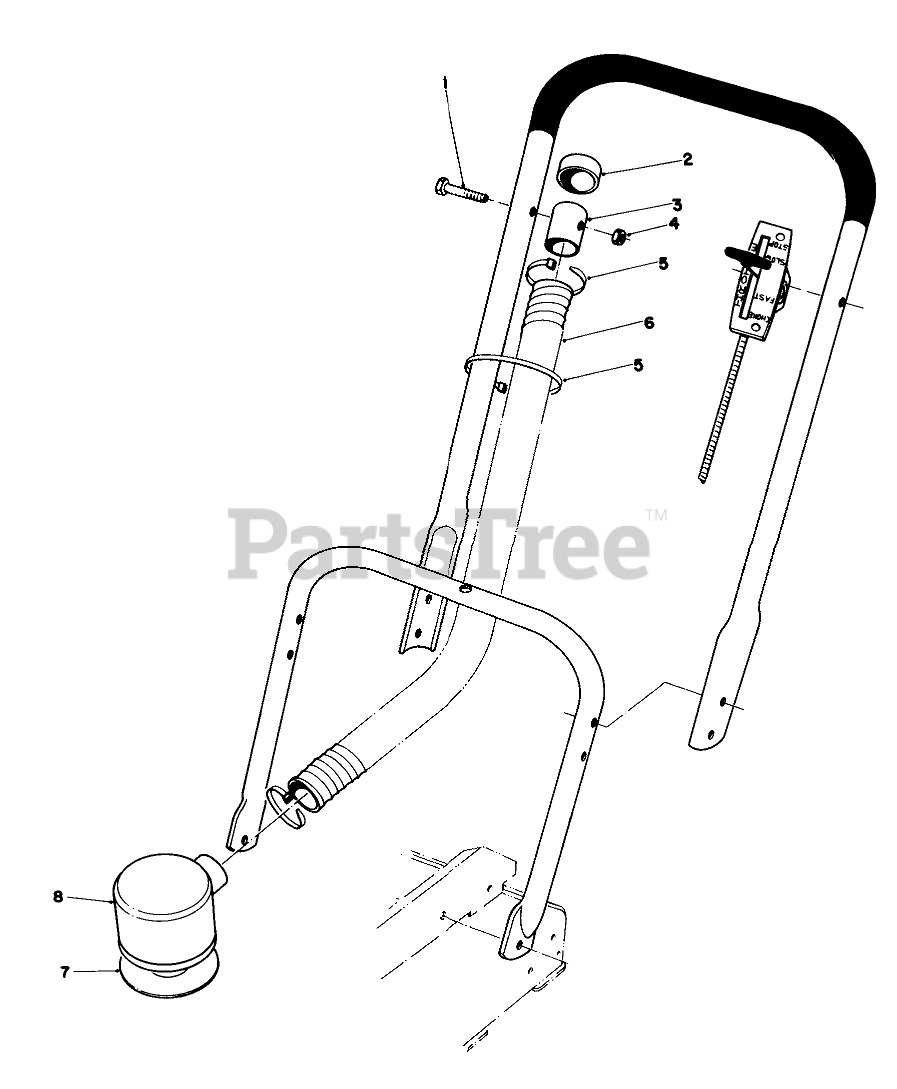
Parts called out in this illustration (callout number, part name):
1	SCREW-HH
2	BLACK CAPLUG
3	AIR CLNR HOSE TIP
5	TIE-CABLE
6	AIR CLEANER HOSE
7	AIR CLEANER BASE
8	Air Cleaner Cover
